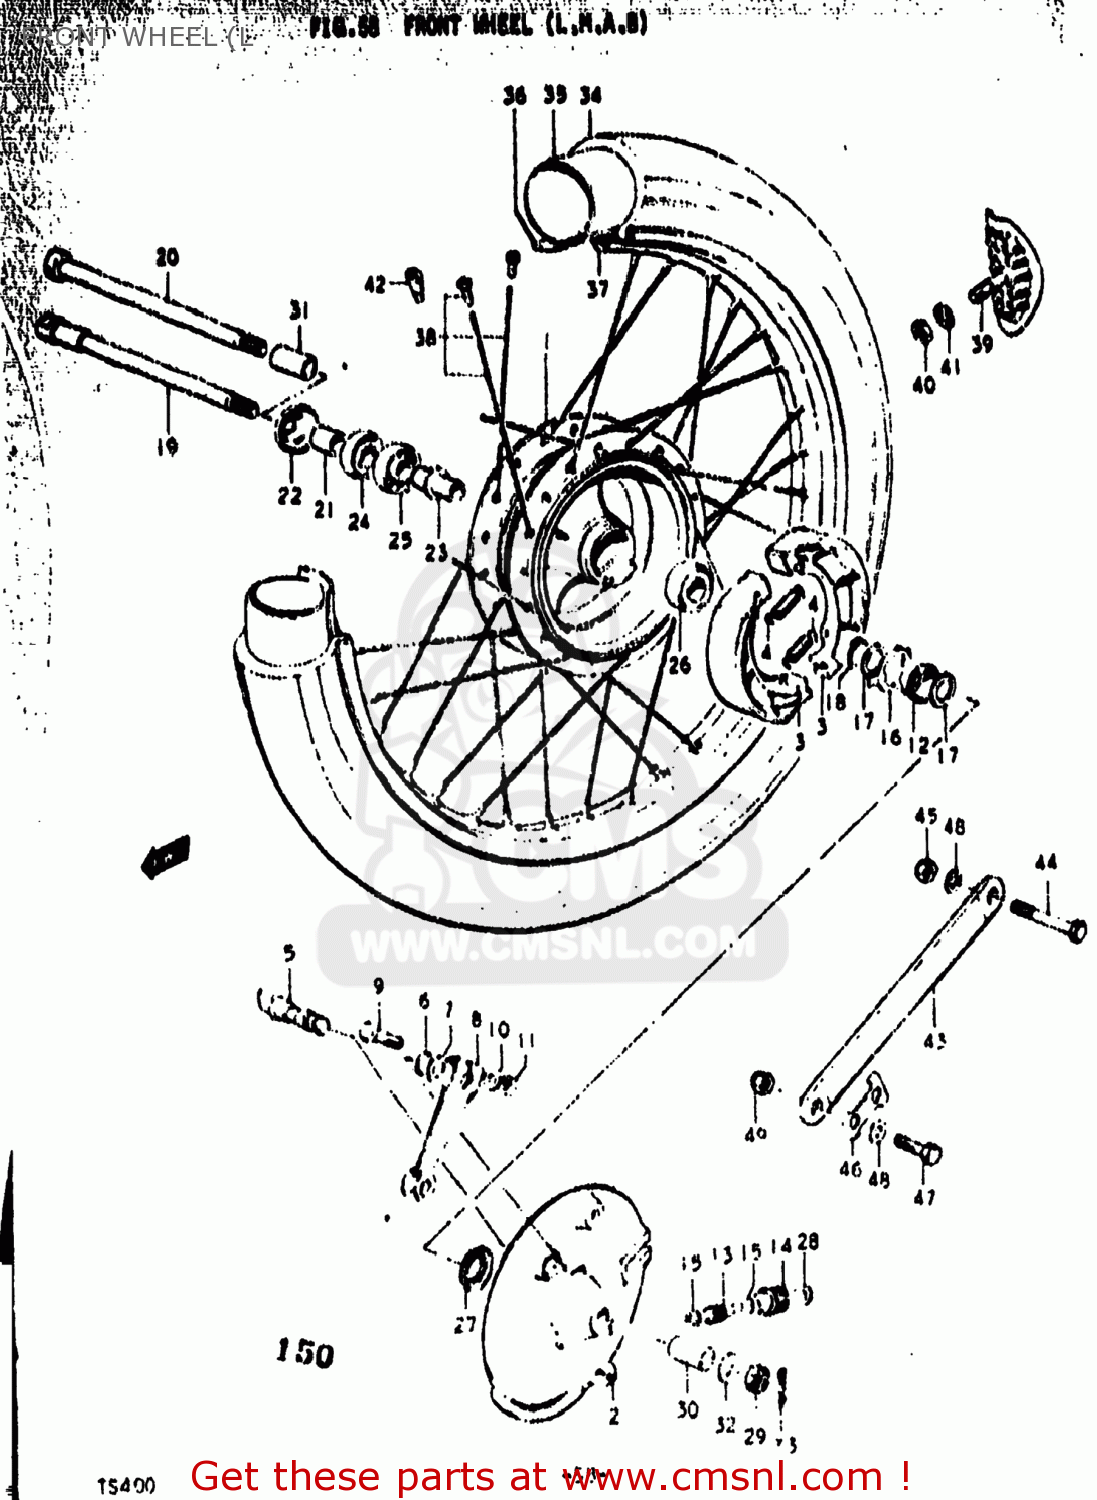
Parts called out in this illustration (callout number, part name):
1	HUB,FRONT
2	PANEL,FRONT HUB
3	SHOE,BRAKE
4	SPRING,BRAKE SHOE
5	CAM,FRONT BRAKE
6	O-RING,BOSS
7	WASHER (15X24X1.6)
8	LEVER,FRONT BRAKE CAM
9	BOLT
10	WASHER
11	NUT
12	GEAR,SPEEDOMETER
13	PINION,SPEEDOMETER
14	BUSHING,SPEEDOMETER PINION
15	WASHER (5.1X9X0.4)
16	DRIVER,SPEEDOMETER GEAR
17	WASHER(22.5X27X1)
18	CIRCLIP
19	AXLE,FRONT
20	AXLE,FRONT
21	SPACER
22	DUST SEAL,FRONT HUB DRUM
23	SPACER,FRONT HUB BEARING
24	OIL SEAL
25	BEARING
26	BEARING
27	OIL SEAL
28	SEAL,OIL(6X10X3)
29	NUT 12MM
30	SPACER
31	SPACER
32	WASHER
33	COTTER PIN
34	TIRE,FRONT
35	TUBE
36	PROTECTOR,WHEEL,INNER
37	RIM,FRONT WHEEL
38	SPOKE SET,FRONT
39	STOPPER,BEAD
40	NUT
41	WASHER
42	BALANCER,WHEEL (50G)
44	BOLT
45	NUT
46	MUD FLAP,FRONT FENDER,LEFT
47	BOLT(8X19.5)
48	WASHER
